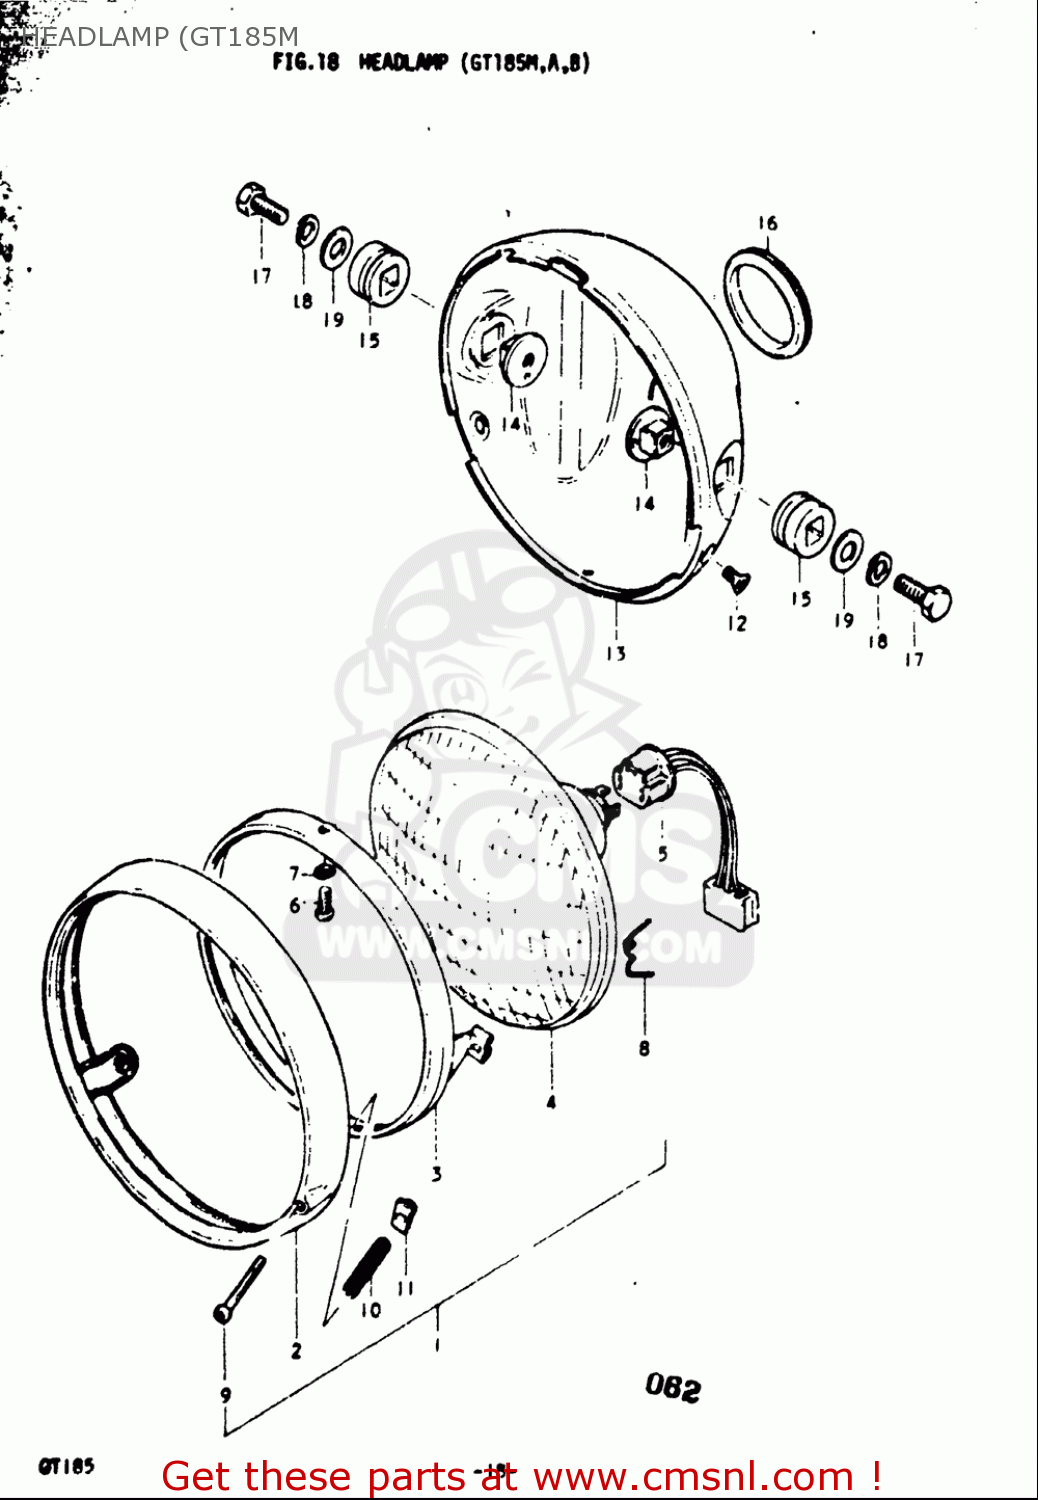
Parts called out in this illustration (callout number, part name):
5	LEAD WIRE,HEADLAMP
6	SCREW
7	WASHER,LOCK
8	SPRING
10	SPRING
11	NUT
12	SCREW
13	HOUSING,HEADLAMP
14	SPACER,HEADLAMP HOUSING
15	CUSHION,HEADLAMP HOUSING
16	GROMMET,HEADLAMP HOUSING
17	BOLT
18	WASHER,LOCK
19	WASHER
